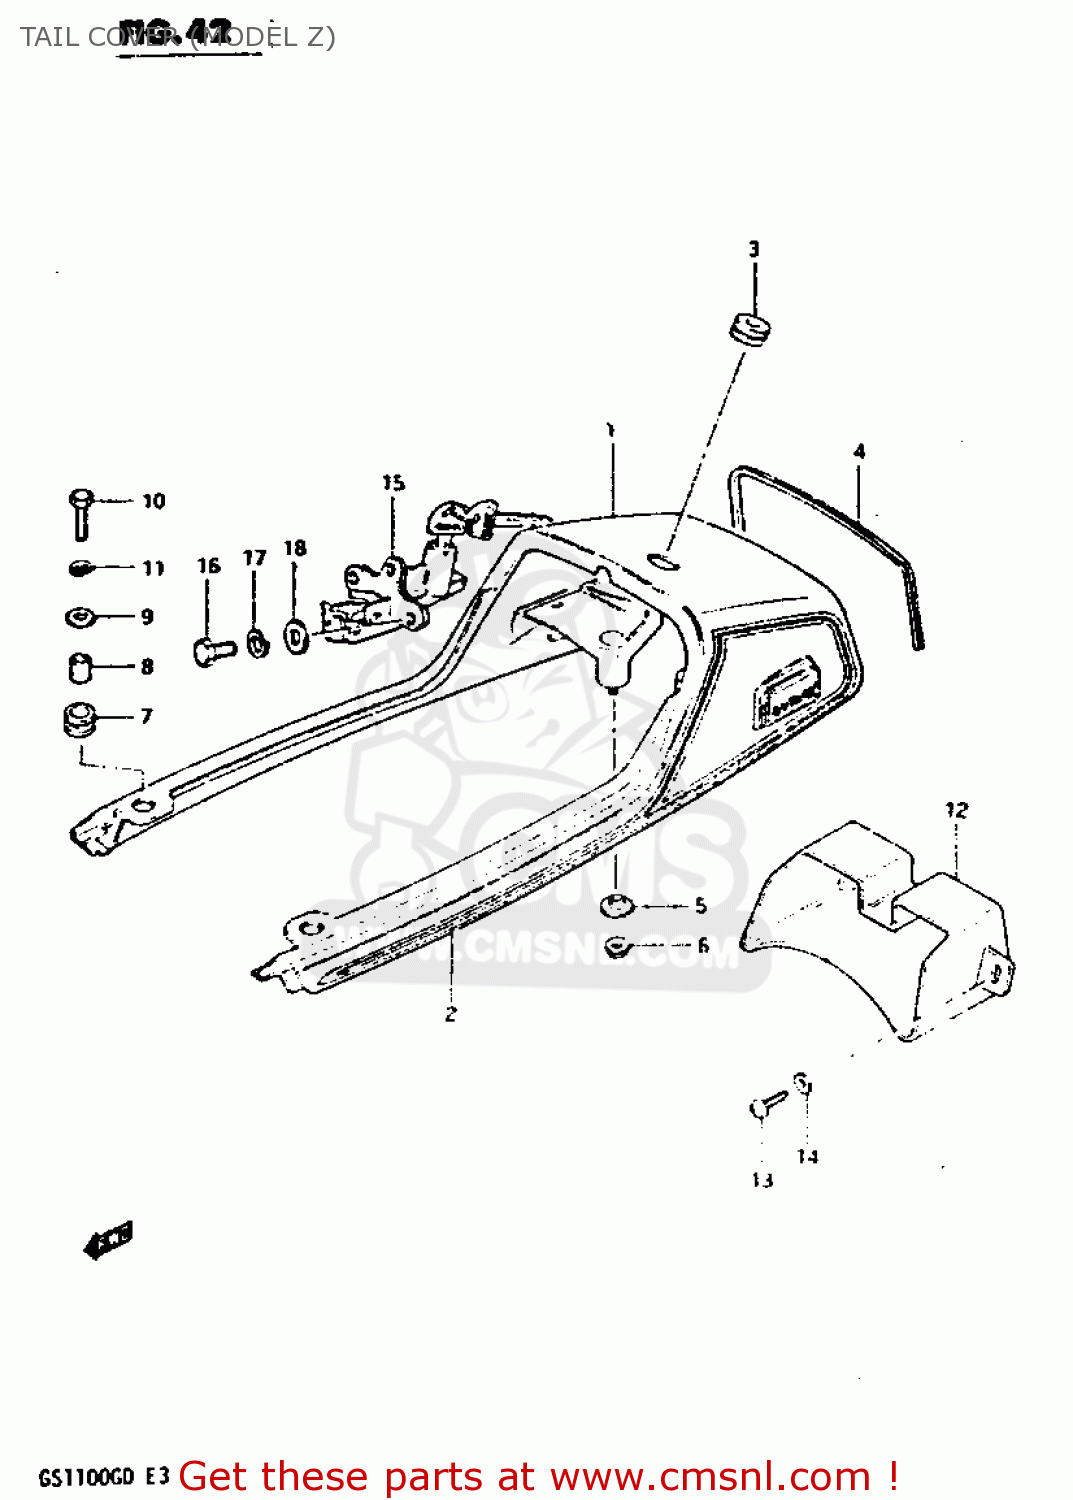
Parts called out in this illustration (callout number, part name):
1	COVER,SEAT TAIL
2	TAPE SET,SEAT TAIL COVER
3	GROMMET,SEAT LOCK HOLE
4	MOLDING,SEAT TAIL COVER
5	WASHER
6	NUT 6MM
7	CUSHION
8	SPACER (7X10X12)
9	WASHER (6.5X24X1.6)
10	BOLT
11	WASHER,LOCK
12	BOX, SEAT TAIL
13	SCREW 6X12
14	WASHER,LOCK
15	LOCK SET,SEAT
16	BOLT
17	WASHER,LOCK
18	WASHER
